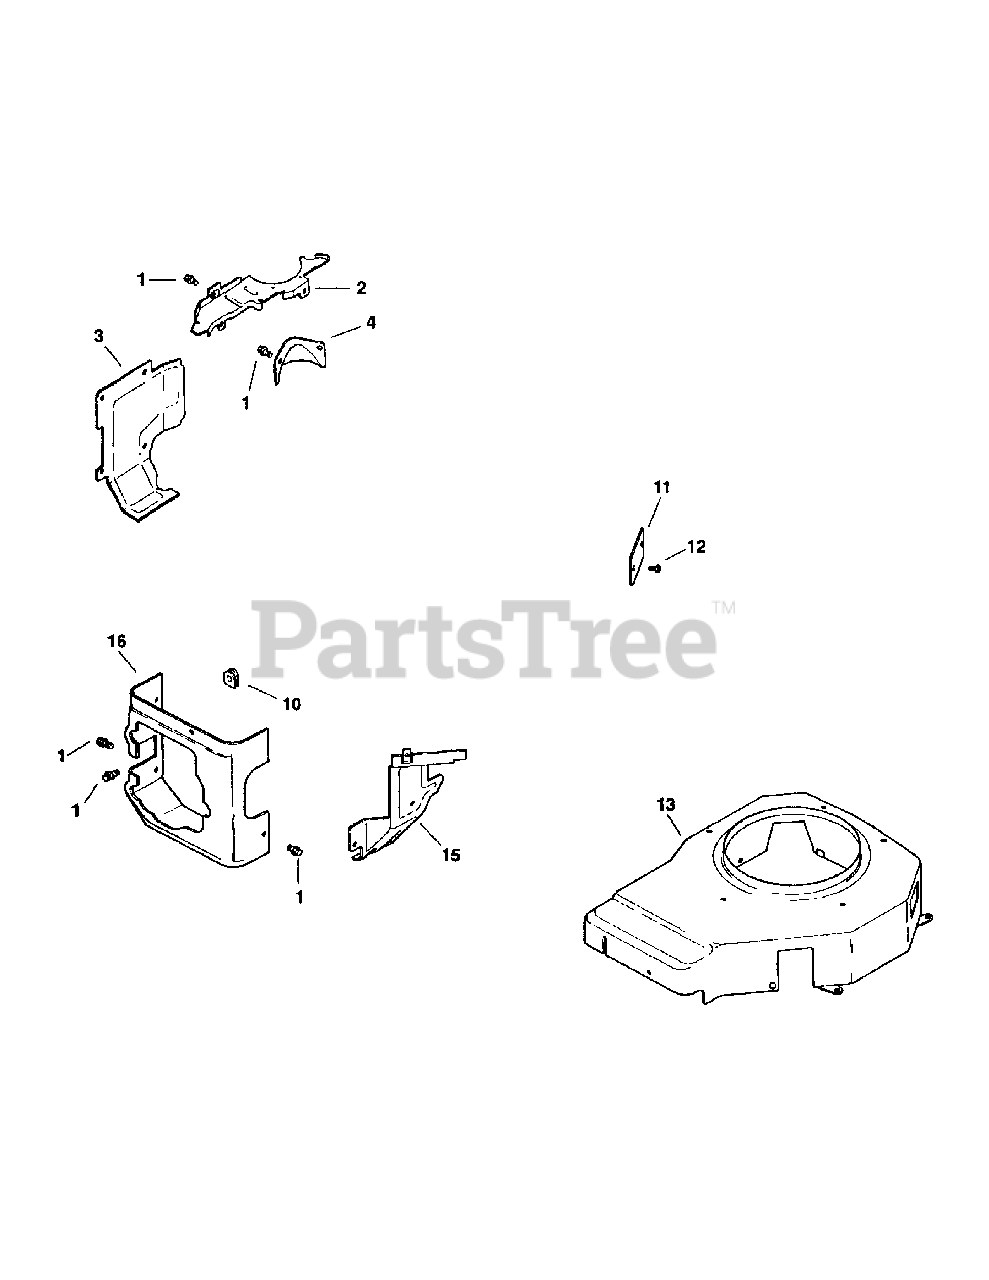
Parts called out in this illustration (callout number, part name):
1	Screw, Hex Flange
2	Plate, Blower Housing Back
3	Baffle, Cylinder Barrel
4	Cover, Starter
10	Grommet, Blower Housing
11	Cover, Regulator
12	Screw, Hex Flange
13	Housing, Blower
15	Baffle, Intake Side
16	Baffle, Cylinder Head
